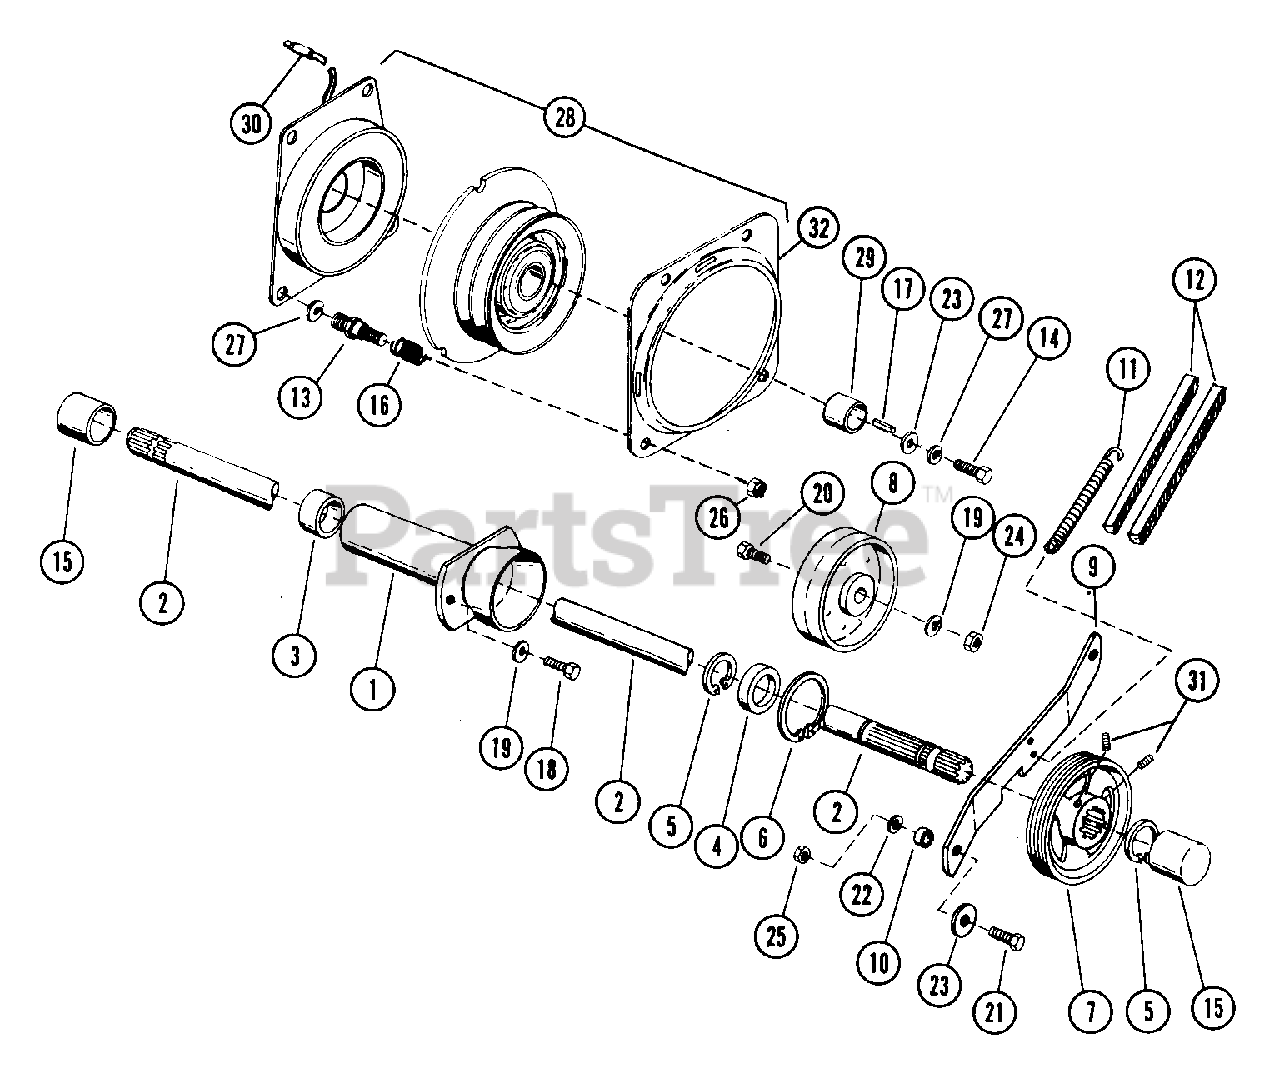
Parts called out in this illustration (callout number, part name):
1	PTO HOUSING SERVICE ASSEMBLY
2	FRONT P.T.O. SHAFT
3	BRG-NEEDLE 1.0X1.25X.93
4	BRG-BALL 1.0X2.0X.56
5	RG-RTNG-EXT 1.00X.042
6	RG-RTNG INT 2.000X.062
7	P.T.O. SHEAVE
8	IDLER-FLAT 3.218X.38
9	IDLER ARM
10	SPACER .512X.747X.208
10	SPACER .516X.749X.265
11	SG-TENS 6.0 FREE LENGTH
12	V-BELT, 4L-WRAPPED (SET)
14	BLT-HEX .44-20X1.00 PL GR2
15	SHAFT COVER
16	SG-COMP WARNER ELEC.
17	KEY-SQ .25X.625X.25 SAE 8630
18	BLT-HEX .38-16X.75 PL GR2
19	WSHR-LK .375X.094 MED PL
20	BLT-HEX .38-16X2.00 PL GR2
21	BLT-HEX .50-13X1.25 PL GR2
22	SHIM SPACER
22	WSHR-LK .500X.151 HVY PL
23	WSHR-FL-STL .568X2.000X.125
24	NUT-HEX .375-16
25	NUT-LK .50-13 PL
26	NUT-LK WARNER
27	WSHR-LK .438X.133 HVY
28	CLUTCH & BRAKE SERVICE ASSEMBL
30	BULLET TERMINAL
31	SCR-SET .32-18X.38 SKHCUPNL OH
